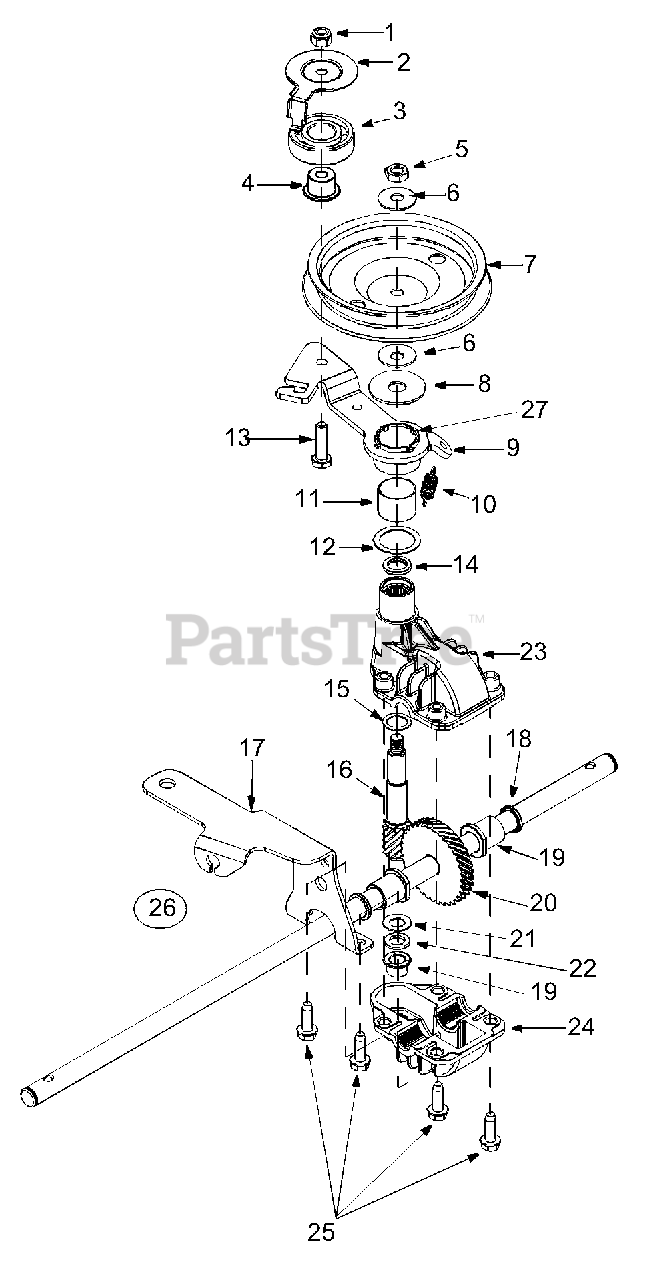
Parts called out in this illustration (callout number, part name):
2	Belt Keeper
3	Ball Bearing
4	Flange Bearing
5	Hex Jam Nut 5/16-24
6	Bell Washer.325 x.930 x.45
7	Pulley, 3.82 x.313 x.68
8	Flat Washer.422 x 1.38 x.060
9	Front Idler Assembly
10	Extension Spring
11	Bearing Sleeve
12	Fl-Wash.865 x 1.145 x.030
13	Hex Screw 1/4-28 x 1.0
14	Needle Bearing.438 x.625 x.500
15	Flat Washer.504 x.700 x.030
16	Pinion Shaft
17	Idler Cable Bracket Assembly
18	Oil Seal
19	Flange Bearing
20	Output Shaft
21	Thrust Washer.375 x.070 x.030
22	Thrust Washer.388 x.625 x.062
23	Upper Housing
24	Lower Housing
25	Hex Screw w/Washer 1/4-20 x.750
26	Transmission Assembly Comp.
